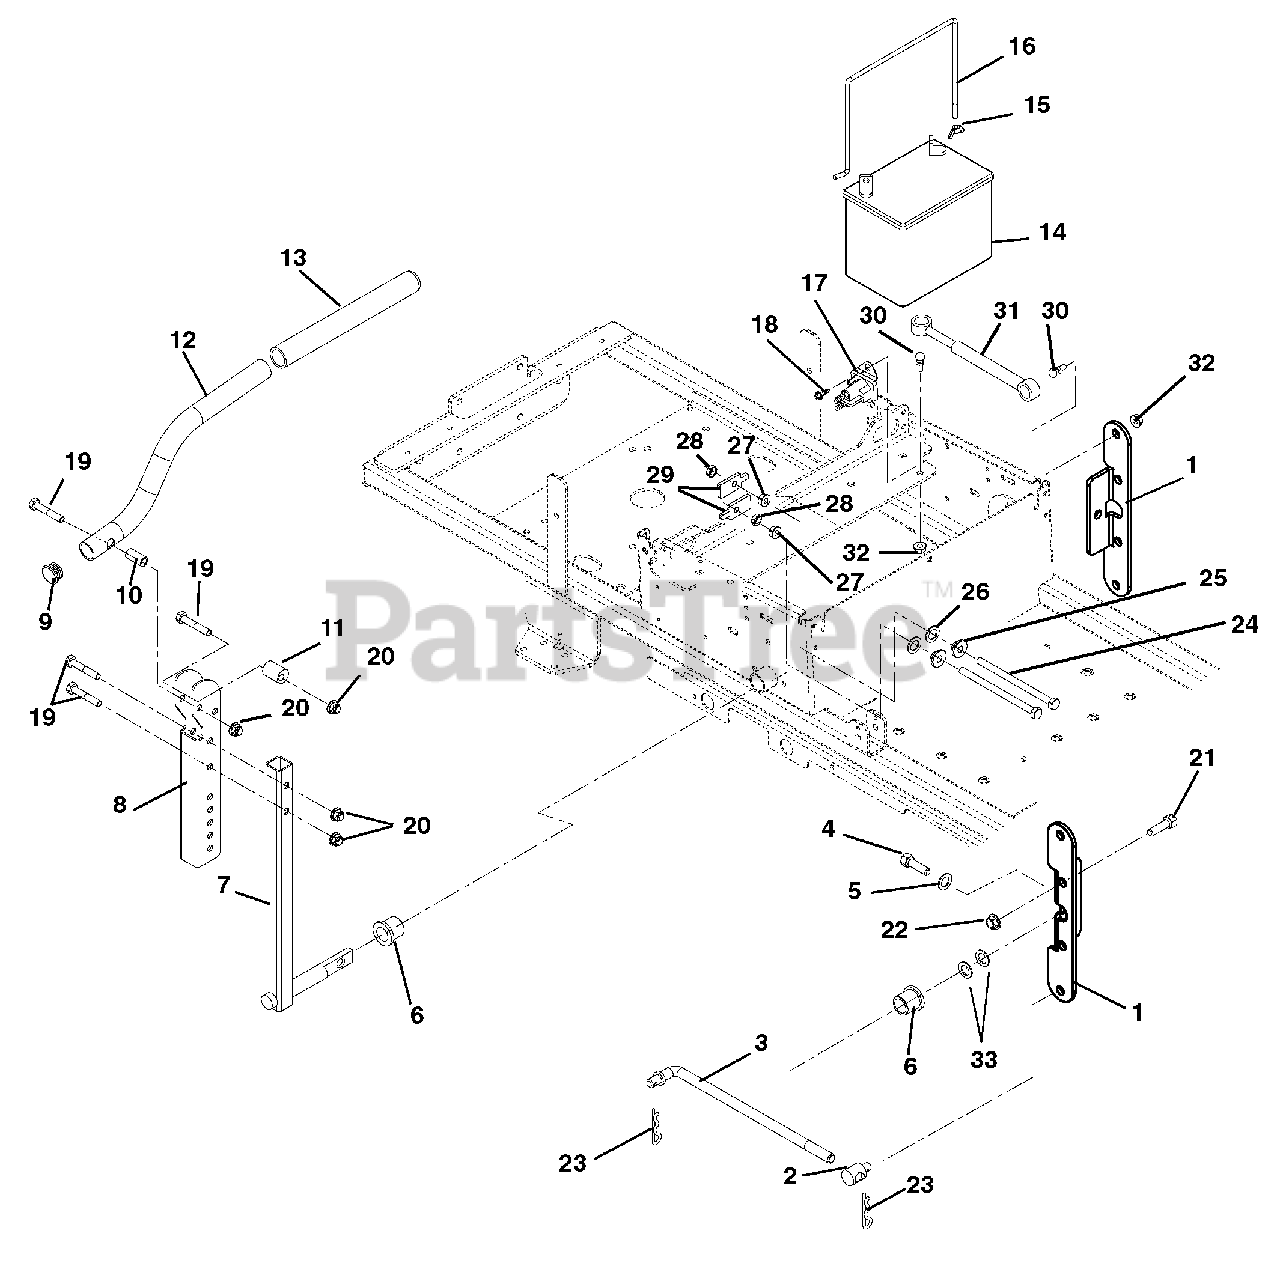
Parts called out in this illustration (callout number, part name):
1	LINK, CONTROL
2	PIVOT, ROD (TRUNNION ) .50
3	LINK,WIREFORM
4	BLT-HEX .38-16X1.0 GR8 YZ EP30
5	WSHR-FL-STL .390X1.5X.125 YWZC
6	BUSHING-1"X.75"X1"
7	WELDMENT, CONTROL ARM
8	CHANNEL, UPPER HANDLEBAR
9	CAPLUG, HANDLEBAR
10	BSHG, SPCR .330X.500X1.01 PM
11	BSHG,ECCEN .328X.750X1.01 PM
12	HANDLE BAR
13	HANDLE GRIP
14	Battery, Exide Sealed Maintenance Free U1-250 (Purchase replacement locally)
15	NUT-LK WING .250-20 YWZC
16	BATTERY ROD
17	SOLENOID, HP RTV
18	@SCR-TAP .25-20X.37 HWH YWZ TR
19	@BLT-HEX .31-18X1.75 GR5 YWZC
20	@NUT-LK-NYL-FLG .31-18 YWZC
21	@BLT-HEX .38-16X1.25 GR5 YWZC
22	NUT-HEX-JAM .375-16 YWZC
23	PIN-HAIR INT .08X.18X1.18 YWZC
24	BLT-HEX,5/16-18X5 G2 HH YWZC
25	BSHG-FLG .32X.500X.344X.880
26	WSHR-FL-STL .52X.827X.062 YWZC
27	@NUT-SPNLK-FLG .312-18 YWZC
28	NUT- JAM .312-18 YWZC
29	STOP TAB
30	STUD- BALL
31	DAMPER, CONTROL
32	@NUT-LK-TOP-FLG .31-18 YWZC
33	WSHR-FL-STL .755X1.25X.125 YZ
